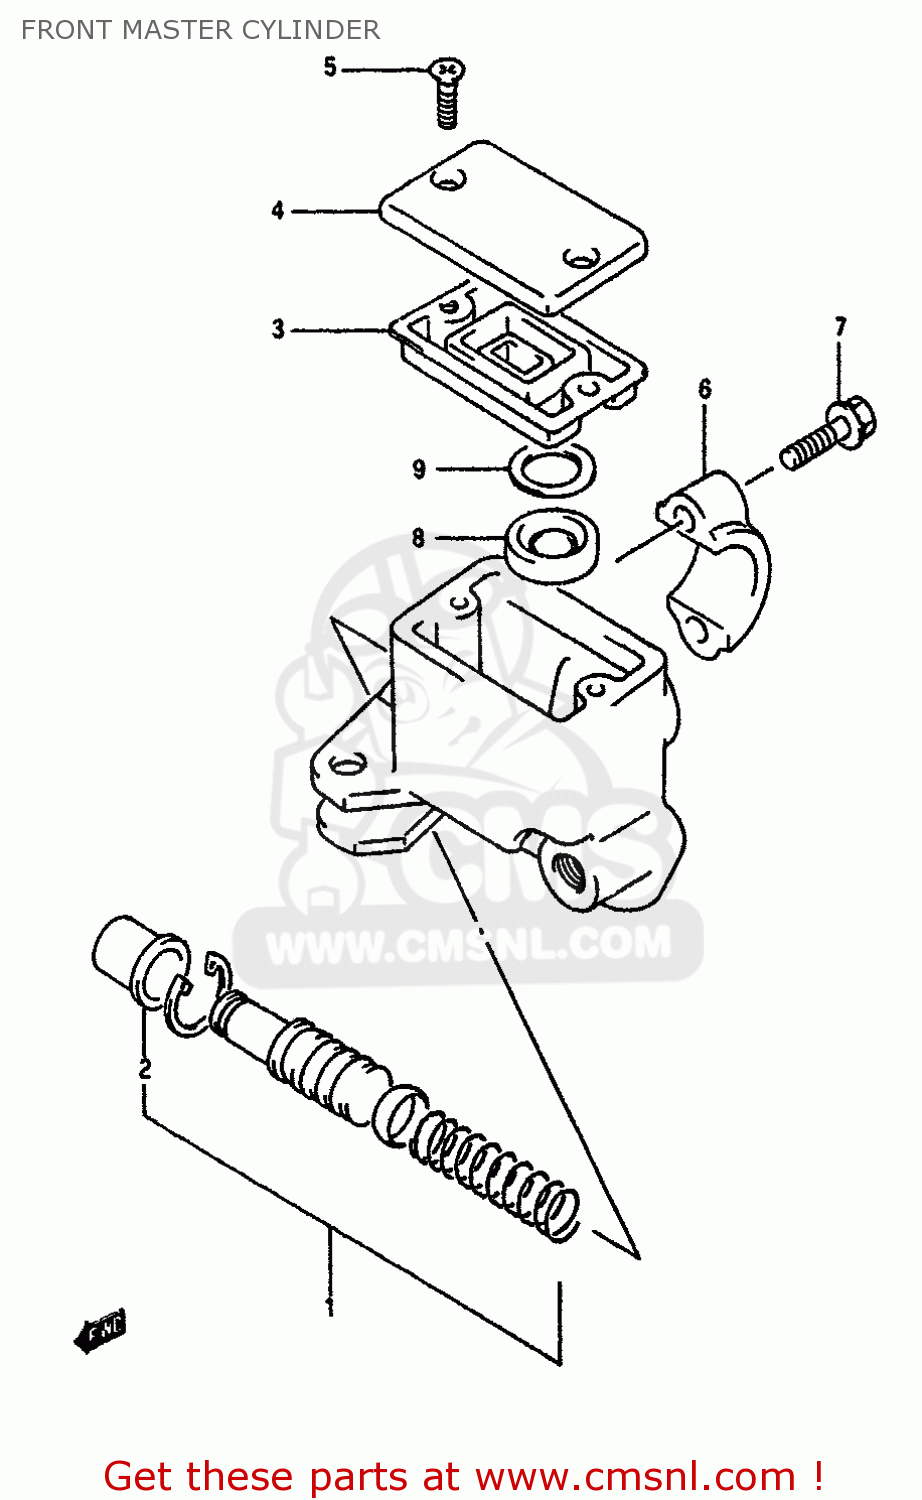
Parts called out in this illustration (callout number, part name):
1	PISTON & CUP SET
2	BOOT
3	DIAPHRAGM
4	CAP
5	SCREW
6	HOLDER
7	BOLT
8	SEPERATOR
9	PLATE
